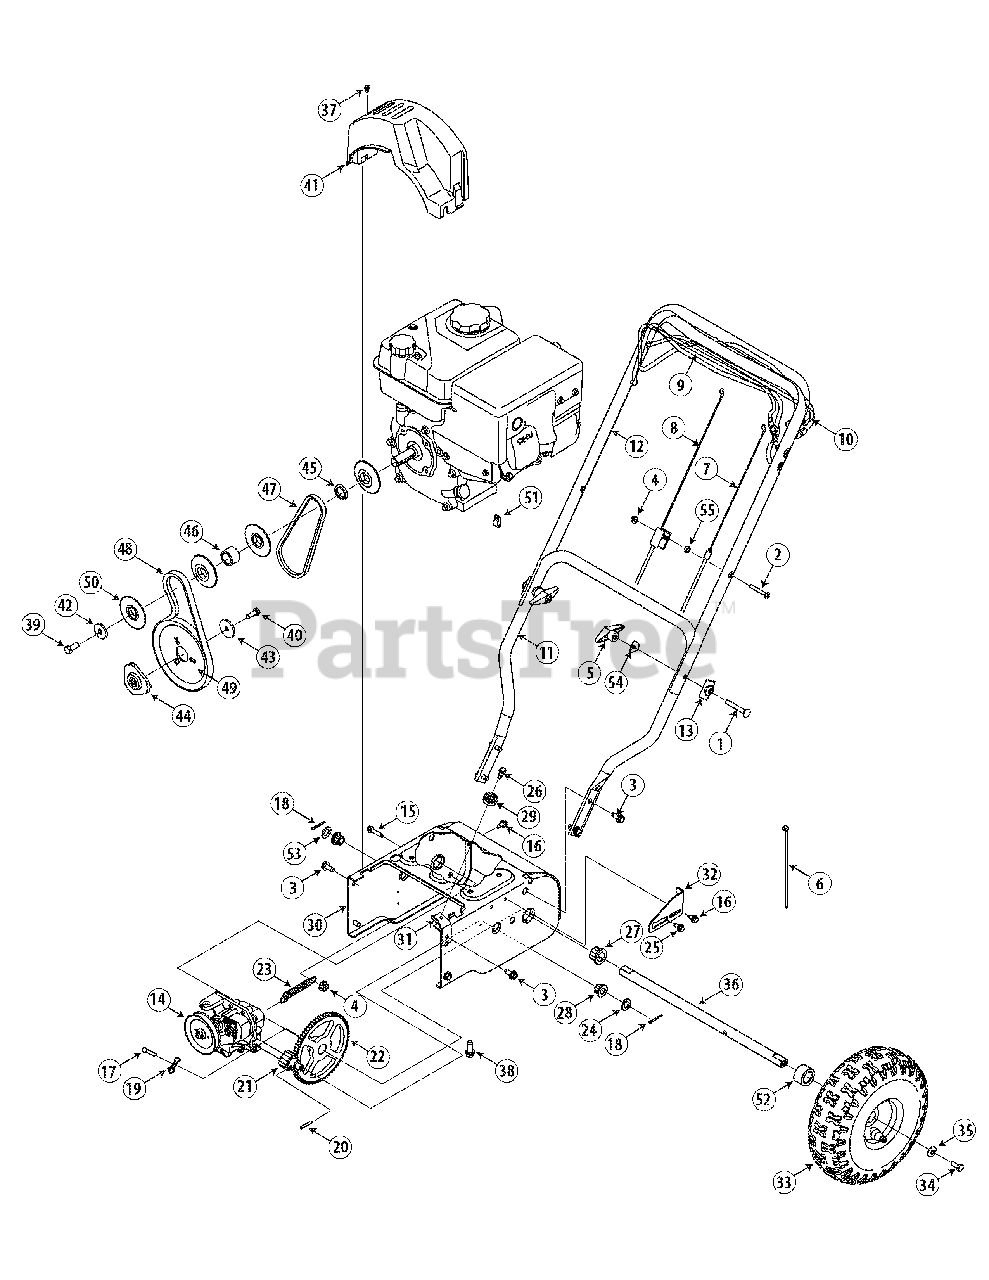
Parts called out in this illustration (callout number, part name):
1	Carriage Screw 5/16-18 x 2.25
2	Mach. Screw 1/4-20 x 1.825
3	Screw 5/16-18 x .75
4	Flange Lock Nut 1/4-20
5	Wing Knob 5/16-18
6	Cable Tie
7	Drive Cable
8	Auger Cable
8	Fitting, Dual Cable
9	Auger Control
10	Drive Control
12	Upper Handle
13	Handle Tab
14	Transmission Assembly
15	TT Screw 1/4-20 x 1.25
16	Screw 1/4-20 x .625
17	Clevis Pin
18	Cotter Pin 1/8 x 1.0
19	Bow Tie Cotter Pin 72
20	Roll Pin
21	Pinion 14T
22	Gear 70T
23	Extension Spring
24	Flat Washer
25	Shoulder Screw 1/4-20
26	Shoulder Screw 1/4-28
27	Hex Flange Bearing
28	Hex Flange Bearing
29	Cable Roller
30	Drive Housing Frame
31	Auger Cable Bracket
33	Wheel Assy Snow Hog Gray
33	Lock Bolt 5/16-24 x .75
35	Bell Washer .34 x .872 x .06
37	Hex Screw #10-16 x .500
38	TT Sems Screw 3/8-16 x 1.0
39	Hex Bolt 3/8-24 x .875
40	Lock Bolt 5/16-24 x .875
41	Belt Cover
42	Flat Washer .406 ID x 1.25 OD
43	Flat Washer .34 ID x 1.50 OD
44	Pulley: Adapter .75 Dia.
45	Spacer .876 x 1.25 x .19
46	Spacer .876 x 1.25 x .86
47	V-Belt 3/8 x 21.108 Lg.
48	V-Belt 3/8 x 26.680 Lg.
49	Auger Pulley
50	Pulley Half
51	Amp Sealed Connector
53	Flat Washer .53 x .93 x .05
54	Saddle Washer
55	Spacer
